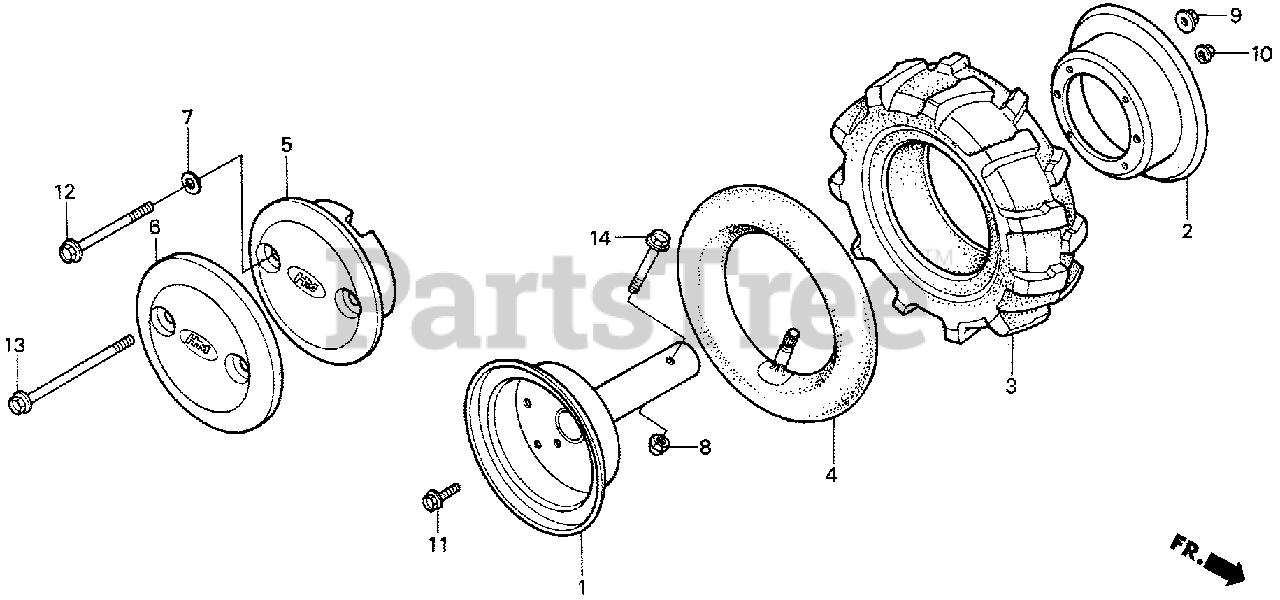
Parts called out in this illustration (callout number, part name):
1	WHEEL A (NOT AVAILABLE)
3	TIRE (3.50-7)
4	TUBE (3.50/4.00-7)
5	WEIGHT A, WHEEL
6	WEIGHT B, WHEEL
7	WASHER, LOCK
8	NUT, SELF-LOCK (10MM)
9	NUT, FLANGE (10MM)
10	NUT-WASHER (8MM)
11	BOLT, FLANGE (8X16)
12	BOLT, FLANGE (10X65)
13	BOLT, FLANGE (10X100)
14	BOLT, FLANGE (10X55)
